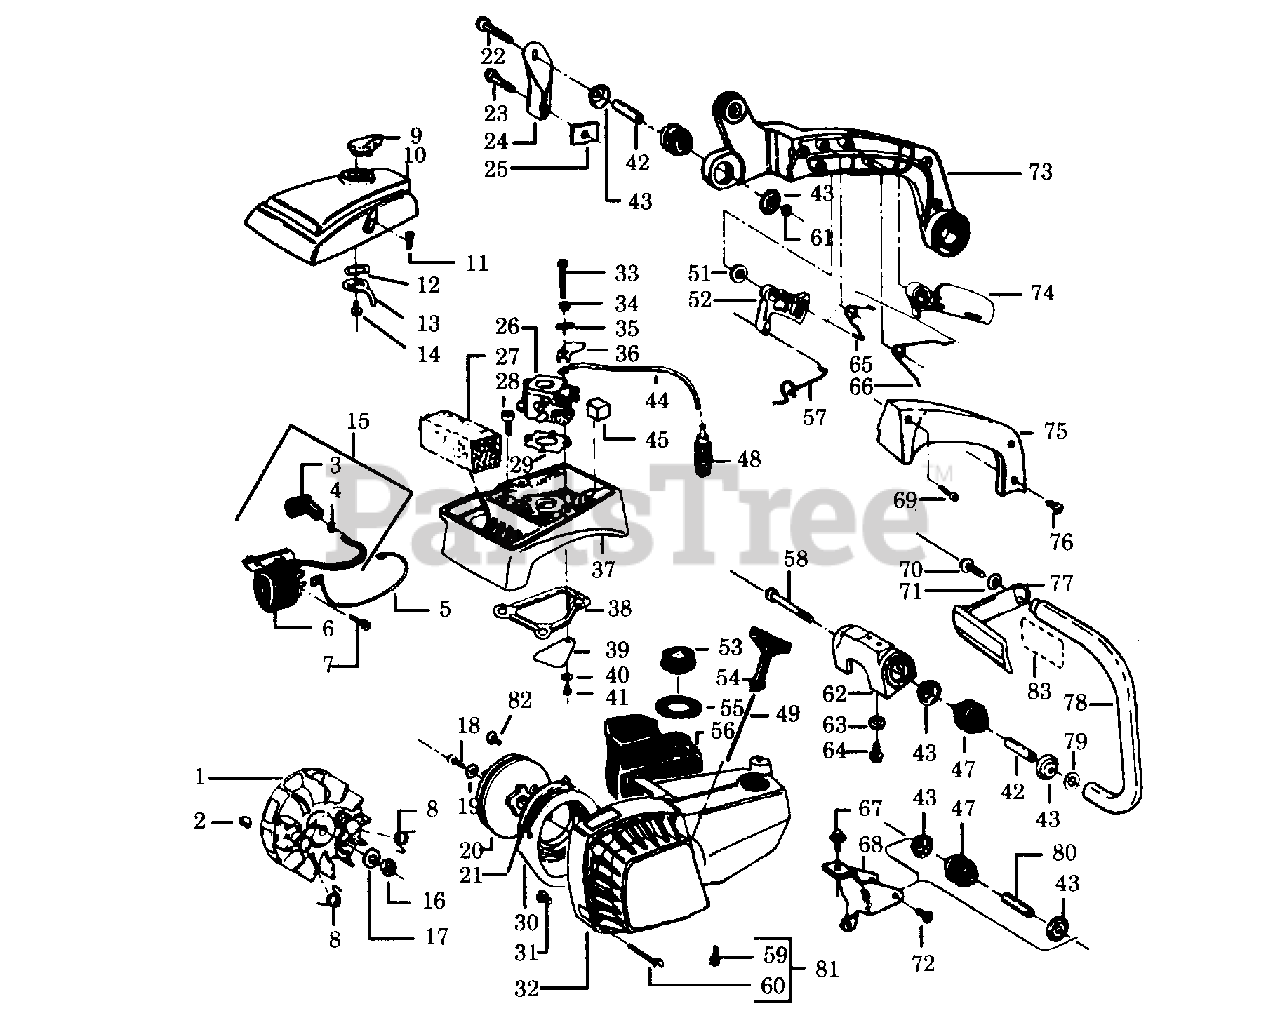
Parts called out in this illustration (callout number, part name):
1	Flywheel Ass'y.
2	Flywheel Key
3	Spark Plug Boot
4	Spark Plug Connector
5	Lead Switch-See Service Ref. 2
6	Ignition Module
7	Screw
8	Starter Dog Spring
9	Choke Knob
10	Carb. Cover
12	Wave Washer
13	Choke Lever
15	Spark Plug Lead
18	Screw
20	Starter Pulley
21	Starter Spring
24	Upper Isolator Bracket
25	Isolator Pad
26	Carb.-See Page 5
27	Air Filter
29	Carb. Gasket
30	Air Intake Baffle
32	Fan Hsg.-See Service Ref. 5
35	Wave Washer
36	Choke Shutter
37	Carb. Hsg.
38	Gasket
39	Reed Valve
43	Isolator Cup-See Service Ref. 1
44	Fuel Line (Bulk No.# 8133)
45	Throttle Wire Boot
47	Isolator
48	Fuel Pick-up Ass'y.
49	Rope Kit
52	Throttle Trigger
53	Fuel Cap Ass'y.
54	Starter Handle
56	Fuel Tank Ass'y.
57	Throttle Wire
62	Lower Isolator Bracket
65	Spring Trigger
68	Rear Isolator Bracket
73	Rear Handle-Right
74	Throttle Lock out Lever
75	Rear Handle-Left
77	Handguard
78	Handlebar w/ Insert
81	Fan Hsg Screws
83	Handguard Decal
